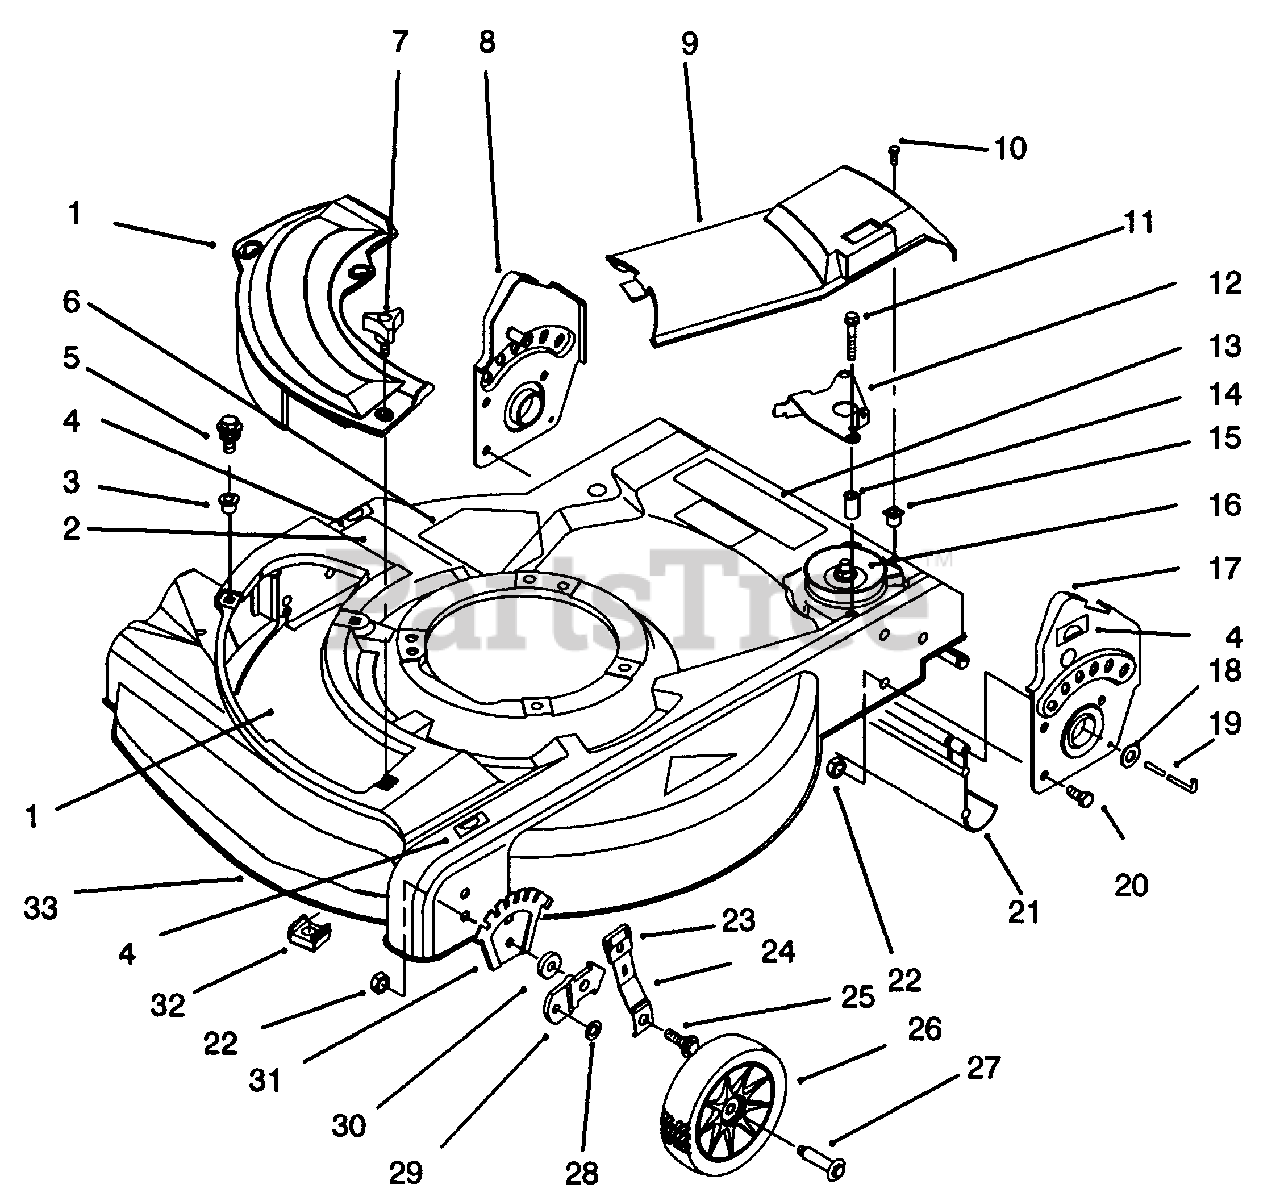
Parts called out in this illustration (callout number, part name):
1	Cover Plate, Mulch
2	Decal-Danger (English)
3	Grommet-Plastic
4	Decal-H.O.C. LH
5	Screw-Thread Forming
6	Decal-Danger (English)
7	Knob
8	Handle Bracket Ass'y-RH
9	Cover-Drive
10	Screw
11	Screw-Thread Forming
12	Guide-Transmission
13	Decal-Warning
13	Decal-Warning (English)
14	Bushing-Actuator Plate
15	Grommet-Shroud Mtg.
16	Gear Case Ass'y
17	Handle Bracket Ass'y-LH
19	Rod-Trailing Shield
20	Screw-Hex. Hd.
21	Shield-Trailing
23	Knob-H.O.C.
24	Arm-Spring
25	Bolt-Shoulder
26	Wheel Assembly-6"
27	Bolt-Wheel
29	Bracket-H.O.C.
31	Plate H.O.C.
32	Nut-Cage
33	Housing & Baffle Ass'y (Incl. Ref. # 1,2,3, & 13)
